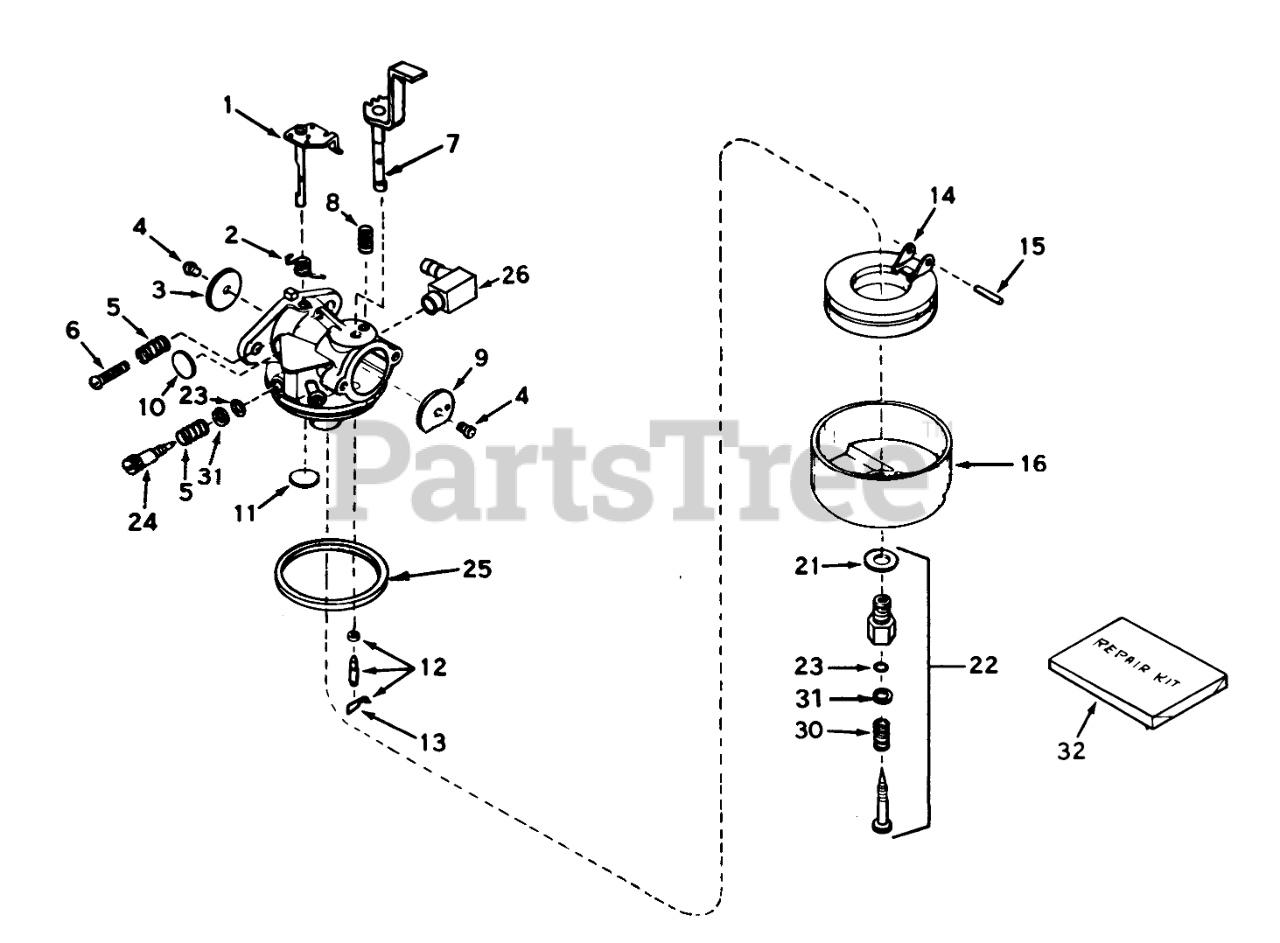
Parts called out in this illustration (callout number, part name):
1	Throttle Shaft and Lever ASM
2	Spring, Throtte Return
3	Shutter-Throttle
4	Screw-Shutter
5	Spring-Tension
6	Screw-Throttle Crack Screw / Idle Speed
7	Shaft & Lever Assy., Choke
8	Spring-Positioning, Choke
9	Shutter-choke
10	Plug-Welch, Idle Mixture Well
11	Plug-Welch, Atmospheric Vent
12	Inlet Needle, Seat & Clip Assy. (Incl. No. 13)
13	Clip-Spring
14	Float,Carburetor
15	Shaft-Float
16	Bowl-Float (no drain)
21	Washer-Bowl Nut
22	Adjustment Screw Assy., Main (Incl. Nos. 21, 23, 30 & 31)
23	"O"Ring
24	Screw, Idle Adj.
25	O Ring-Bowl, Float
26	Fitting-Fuel
32	Kit-Repair
